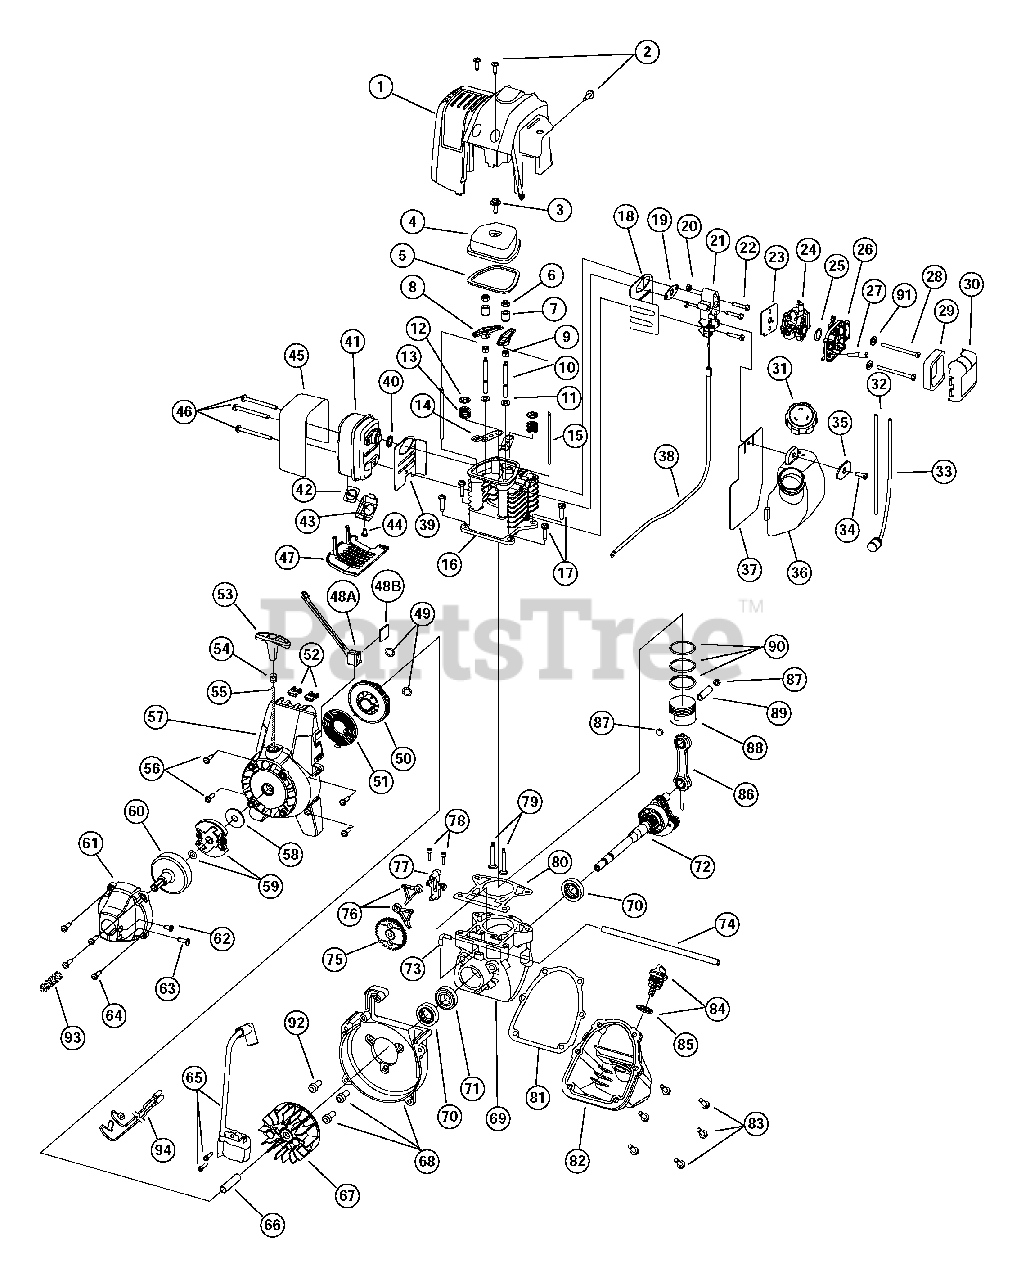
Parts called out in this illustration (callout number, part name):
1	Engine Cover
2	Engine Cover Screws
3	Valve Cover Screw
4	Valve Cover
5	Valve Cover Gasket
6	Rocker Adjustment Nut
7	Rocker Arm Pivot
8	Rocker Arm
9	Hex Nut
10	Rocker Arm Stud
12	Valve Spring Retainer
13	Valve Spring
14	Push Rod Guide
15	Push Rod
16	Cylinder Head
17	Cylinder Screw
18	Intake Baffle
19	Carburetor Mount Gasket
20	Nut
21	Carburetor Mount
22	Carburetor Mount Screw
23	Carburetor Gasket
24	Carburetor with Primer
25	O-Ring, Carburetor
26	Air Filter Assembly
28	Air Filter Mounting Screw
29	Air Filter
30	Air Filter Cover
31	Fuel Cap
32	Fuel Return Line
33	Fuel Pick-Up Line with Filter
36	Fuel Tank Assembly
37	Fuel Tank Shield
38	Throttle Cable
39	Muffler Baffle
40	Muffler Gasket
41	Muffler
42	Spark Arrestor Screen
43	Screen Cover
45	Muffler Shield
46	Muffler Mounting Screw
47	Muffler Cover
48A	Switch with Wires
48B	Grommet
49	Pulley Retainer Assembly
50	Recoil Pulley
51	Recoil Spring
52	Nut Clip
53	Pull Handle
54	Rope Guide
56	Starter Housing Screw
57	Starter Housing Assembly
58	Clutch Washer
59	Clutch with Spacer
60	Clutch Drum
61	Clutch Cover
62	Anti-Rotation Screw
64	Clutch Cover Screw
65	Ignition Module with Screws
67	Flywheel
68	Shroud Assembly with Screws
69	Crankcase Assembly
70	Oil Seal
71	Bearing
72	Crankshaft
73	90° Elbow
74	Breather Hose
75	Cam Gear
76	Cam Follower
77	Cam Bracket
78	Cam Bracket Screw
79	Valves, Intake and Exhaust
80	Cylinder Gasket
81	Oil Pan Gasket
82	Oil Pan
83	Oil Pan Screw
84	Dipstick Assembly
86	Connecting Rod
87	Wrist Pin Button
88	Piston
89	Wrist Pin
90	Piston Ring Set
92	Compression Spring
93	Ignition Wire
